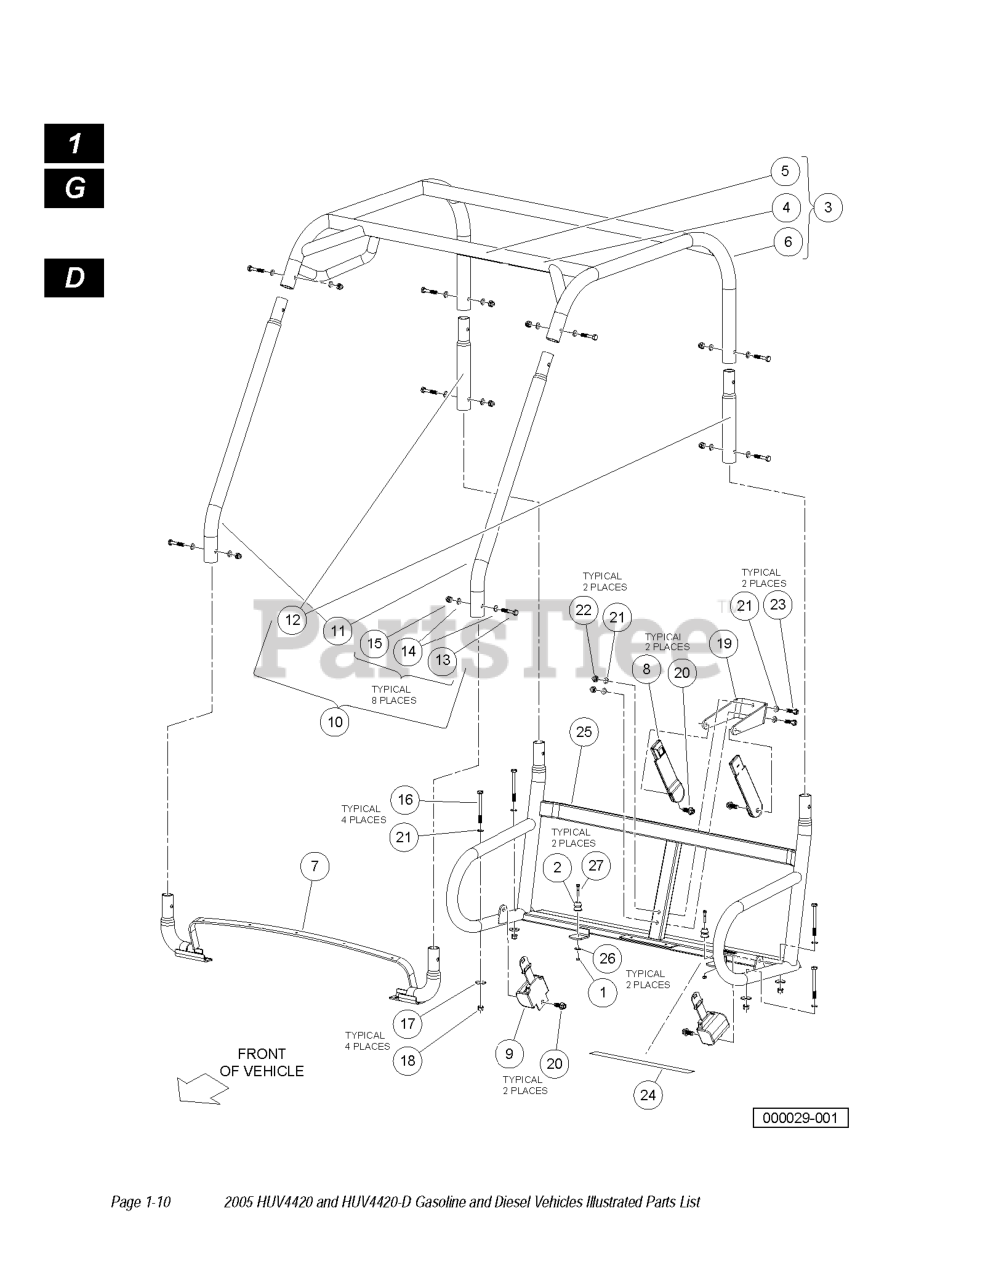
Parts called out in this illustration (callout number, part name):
1	LOCKNUT, M6-1.00 NYLON INSERT
2	SEAT HOLDER BASE
3	WELDMENT, TOP, ROPS
4	DECAL, WARNING UNDER 16
5	DECAL, WARNING-CERTIFIED ROPS
6	Weldment, ROPS, Top, Unlabeled
7	WELDMENT, SUPP, COWL, ROPS
8	BUCKLE, SEAT BELT W/ SLEEVE
9	RETRACTOR, SEAT BELT
11	TUBE, SUPP, FRONT, ROPS
12	TUBE, SUPP, REAR, ROPS
13	BOLT
14	WASHER, HARD, M10, ZN-NI/BLK
15	NUT, HEX CAP, M10, ZN-NI/BLK
16	BOLT, M10 X 100, ZN-NI/BLK
17	WASHER HARD, M10
18	NUT FLG M10 X 1.5 MECH DEF
19	BRKT, SEATBELT, BOLT-ON
20	SCREW,M12X1.75X30 THD FORM BLK
21	WASHER, HARD, M10, ZN-NI/BLK
22	NUT, HEX CAP, M10, ZN-NI/BLK
23	BOLT, M10 X 45, ZN-NI/BLK
24	BARRIER, HEAT, NEOPRENE, AWD
25	WELDMENT, SUPP, SEAT, ROPS
26	WASHER 1/4 FLAT
27	BOLT, M6 X 1 X 45
